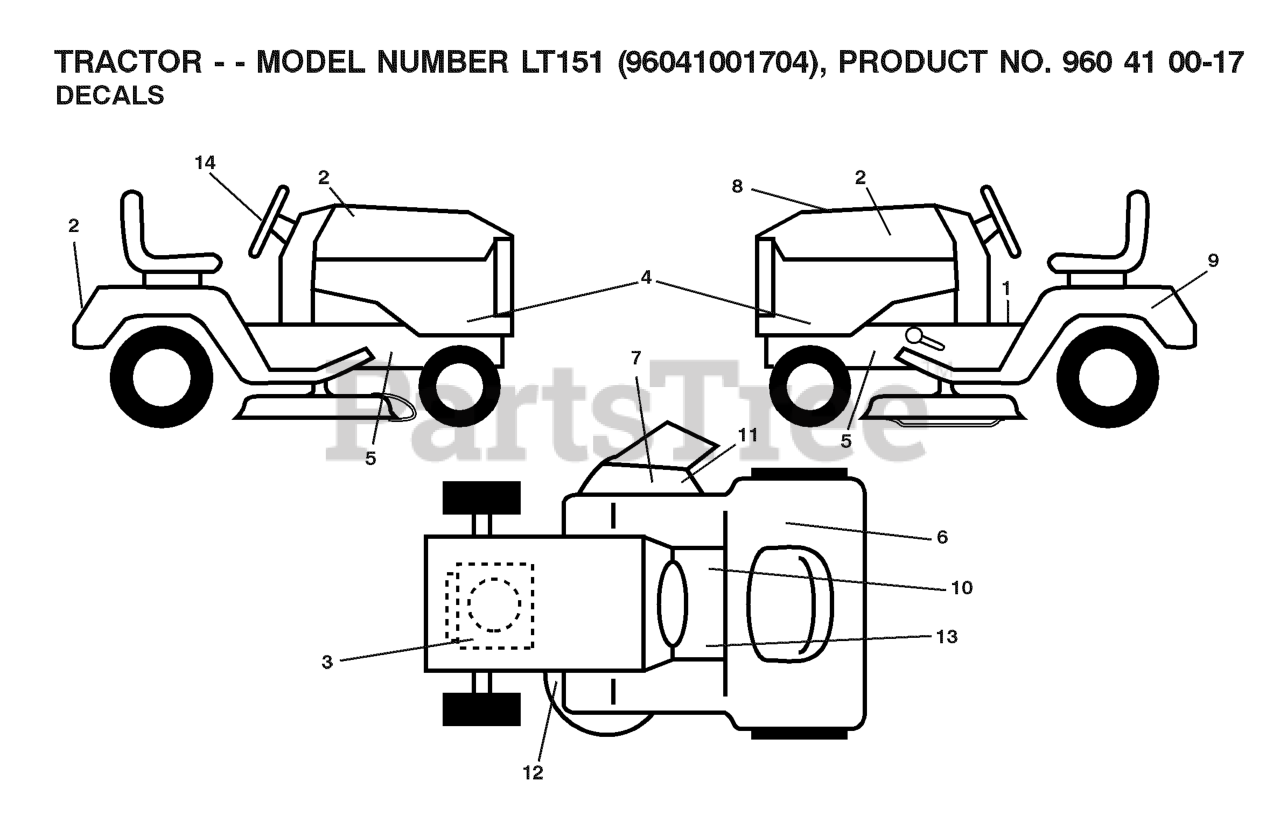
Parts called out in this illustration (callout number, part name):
1	LABEL
2	DECAL.HOOD.NAMELOGO.HUSQ
3	DECAL
6	Decal, Fender 100 DB/CE
7	DECAL.INTERNATIONL.CUTFINGER
9	DECAL BTRY SYMBOLS
10	DECAL PARK BRAKE
11	DECAL, DEFLECT WARNING
12	DECAL.V-BELT.SCHEMATIC.36/38/9
13	DECAL
14	DECAL.WHEEL.STRG.LGN.H
